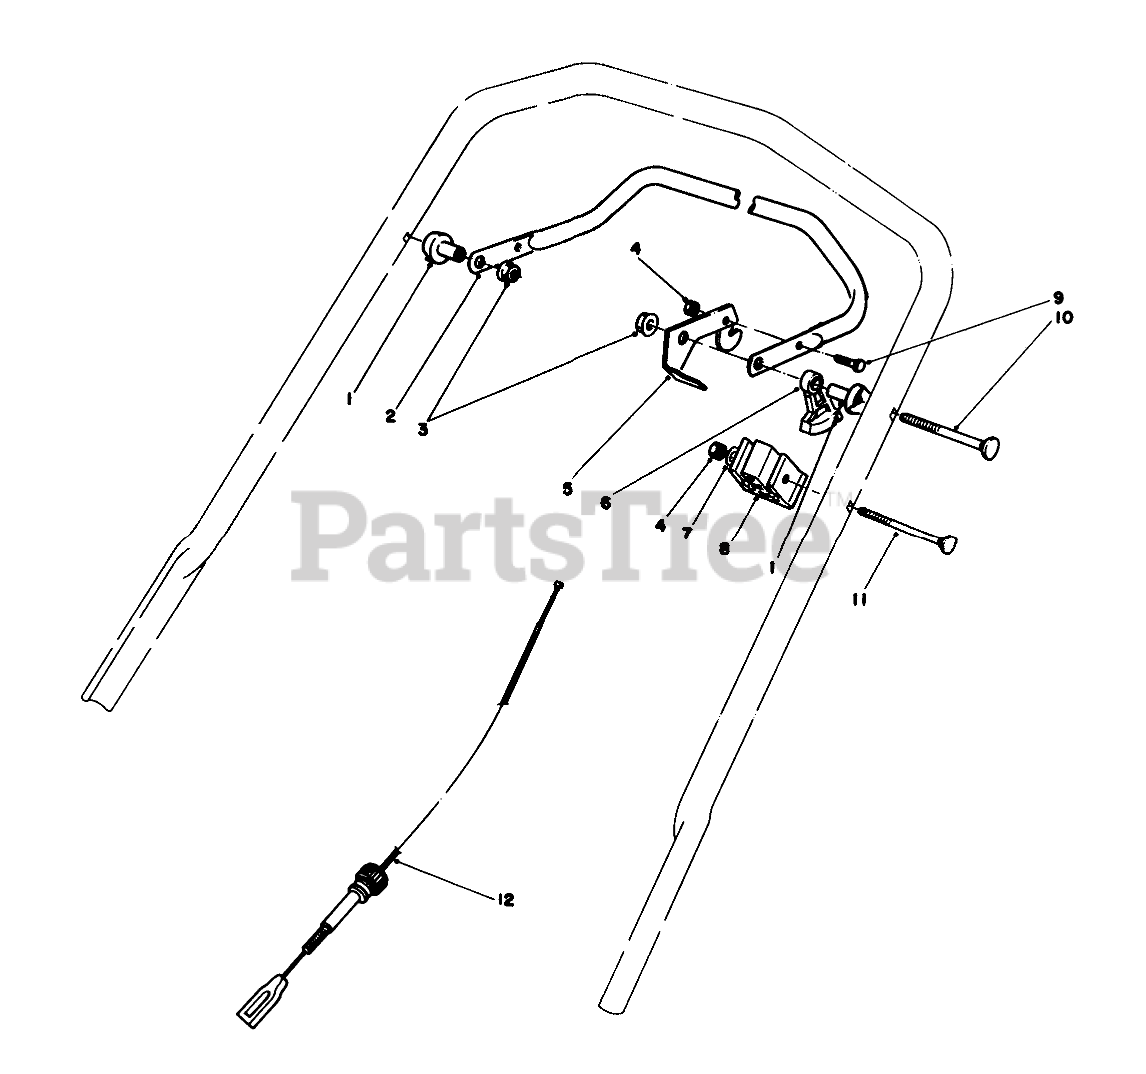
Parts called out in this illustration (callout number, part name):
1	SPACER-SUPPORT
2	Bar-Control
3	NUT-LOCK, NI
4	NUT-LOCK, NI
5	CONTROL LEVER
6	LEVER-TRACTION
7	WASHER-FLAT
8	SUPPORT-CABLE
9	SCREW-HH
10	5/16-18 X 2 HNDLE SCREW
11	HANDLE SCREW
12	CABLE-TRACTION
